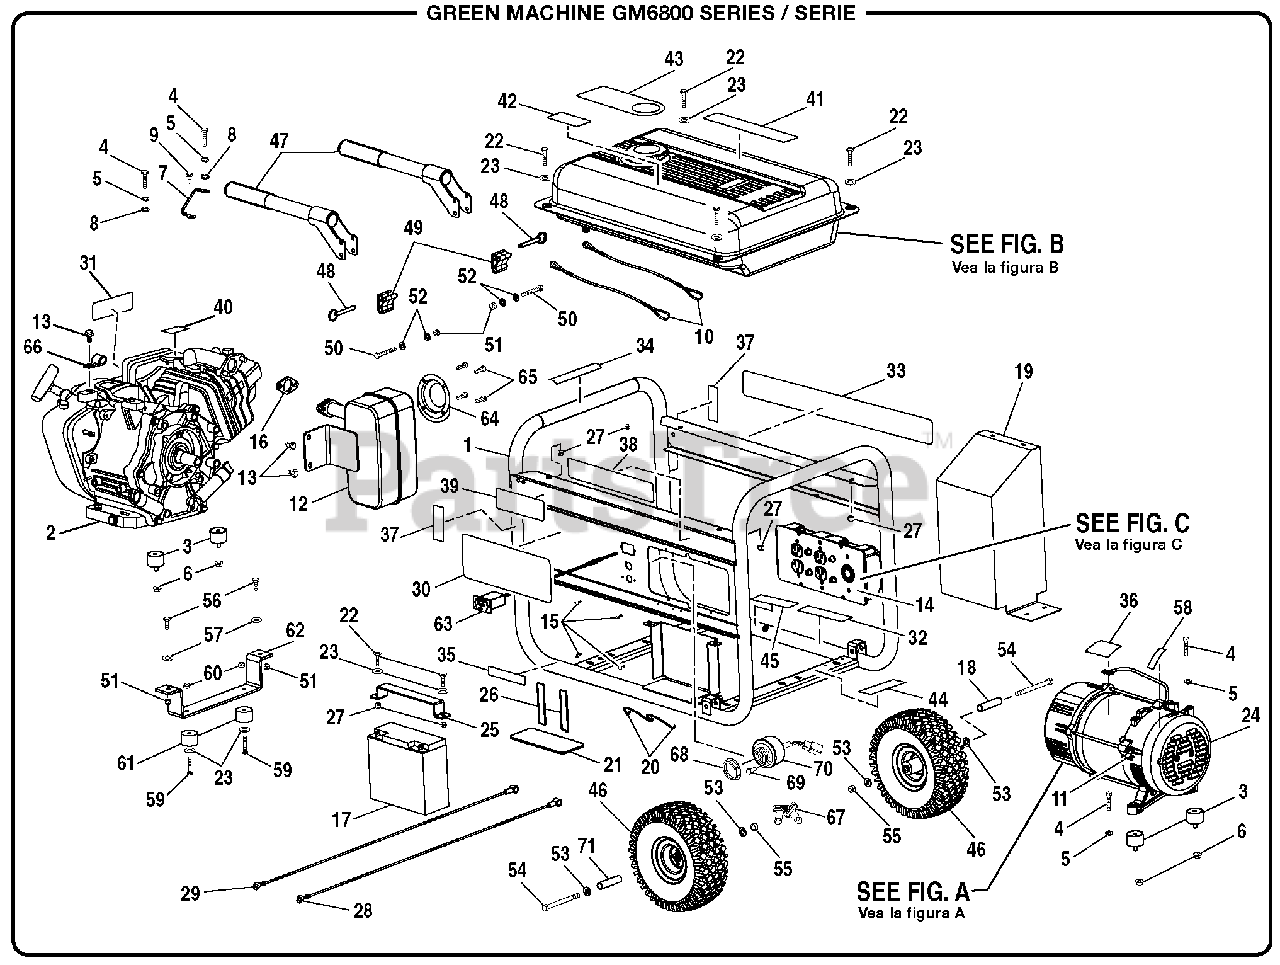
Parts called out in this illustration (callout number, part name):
1	Carrier Assembly
4	Bolt (5/16-18 x 1-1/2 in., Hex Hd.)
5	Lock Washer (5/16 in.)
6	Flange Nut (5/16-18, Hex Hd.)
7	Ground Wire Assembly
8	Star Washer (5/16 in.)
9	Bolt (5/16-18 x 3/4 in., Hex Hd.)
10	Lanyard (3/16 in.)
11	Ground Lug
13	Bolt (5/16-24 x 5/8 in.)
14	Control Panel Assembly
15	Screw (6-20 x 3/8 in.)
16	Muffler Gasket (supplied by Yamaha)
17	Battery
19	Heat Shield
20	Cord Retainer
21	Battery Box Gasket
22	Bolt (1/4-20 x 1 in., Hex Hd.)
23	Washer (1/4 in.)
24	Generator Head w/AVR
25	Battery Hold Down Bracket
26	Gasket (Battery Hold Down Bracket)
27	Lock Nut (1/4-20)
28	Battery Cable (Red)
29	Battery Cable (Black)
30	Logo Label
31	Starting Instructions Label
32	Hot Surface Label
33	Danger Label
34	Fire Danger Label
35	Engine Lubricant Label
36	Data Plate Label
37	Locking Pin Label
38	Yamaha Label
39	Electric Start Label
40	Choke Label
41	Quick Start Label
42	CPSC Label
43	Danger Hang Tag
44	Ground Warning Label
45	Combustion Warning Label
46	Wheel Assembly
47	Handle Assembly
48	Release Pin (5/16 x 2 in.)
49	Handle Bracket Spacer
50	Bolt (5/16-18 x 2-1/4 in., Hex Hd.)
51	Lock Nut (5/16)
52	Washer (5/16 in.)
53	Washer (3/16 in.)
54	Bolt (3/8-16 x 4-1/4 in., Hex Hd.)
55	Nut (3/8-16)
56	Bolt (5/16-18 x 1 in., Hex Hd.)
57	Flat Washer (5/16 in.)
58	Ground Label Icon
59	Bolt (1/4-20 x 1-1/2 in., Hex Hd.)
60	Lock Nut (1/4-20)
61	Rubber Foot
62	Front Foot
63	Hour Meter (120 Volt)
64	Spark Arrestor
65	Screw (8-32 x 3/8 in., Pan Hd.)
66	J-Clamp (1/2 in.)
67	Switch Key
68	Switch Key Nut
69	Locating Pin
